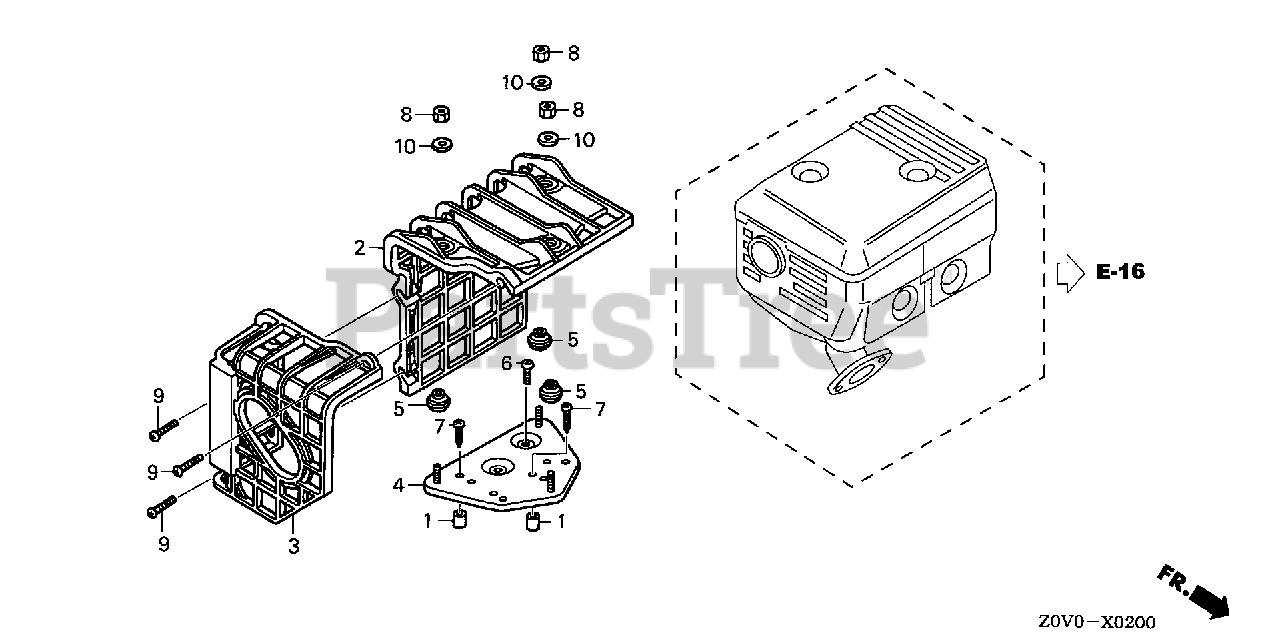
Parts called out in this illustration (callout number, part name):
1	COLLAR, AIR CLEANER HOUSING
2	COVER, MUFFLER
3	COVER, RR. MUFFLER
4	BASE, MUFFLER COVER
5	SPACER, MUFFLER COVER
6	SCREW, TAPPING (5X8)
7	SCREW, TAPPING (5X25)
8	NUT, HEX. (5MM)
9	SCREW-WASHER (6X20)
10	WASHER, PLAIN (5MM)
